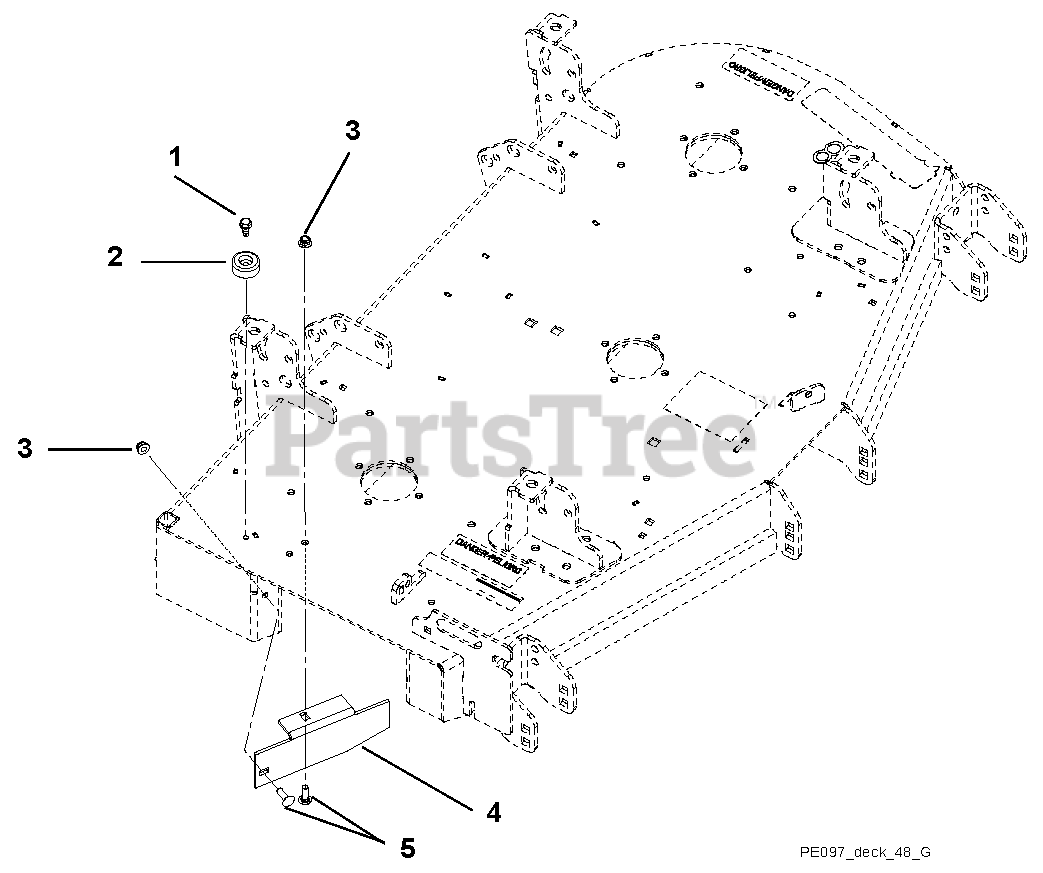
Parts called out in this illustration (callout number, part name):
1	Screw, Tapping .31-18 x .75 Hex Washer Head
2	Bumper, Recessed 1.50 x .63 w/.31 Thru Hole
3	Nut, Locking Nyloc Flange .31-18
4	Discharge Baffle
5	Bolt, Round Head Square Neck .31-18 x 1.00
